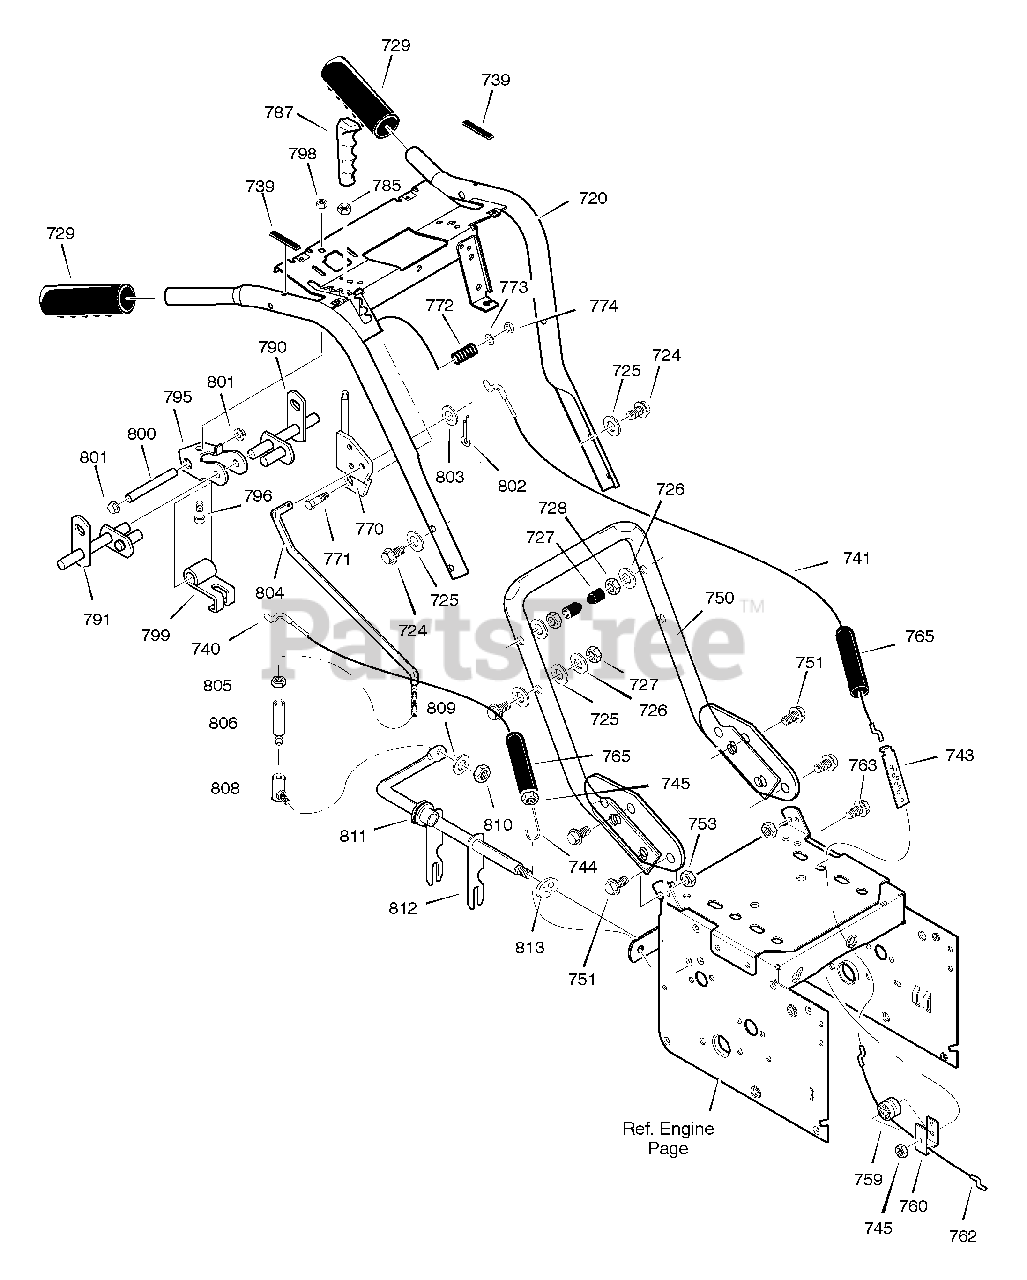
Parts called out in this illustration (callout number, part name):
720	ASSY, HANDLE
724	SCREW
725	WASHER, FLAT
726	WASHER
727	NUT
728	STOP, PLASTIC
729	GRIP, HANDLE
739	BUMPER
740	CABLE, AUGER CLUTCH
741	CABLE, DRIVE
743	BRKT, CABLE ADJ
744	SPRING, CLUTCH
745	NUT, HEX
750	HANDLE, LOWER
751	SCREW
759	SPOOL, CABLE
760	BRKT, SPOOL
762	CABLE, LOWER DRIVE
763	BOLT, HEX 1/4-20 x 1.5
765	BOOT, CABLE
770	BRACKET, SHIFT
771	SCREW
772	SPRING
773	WASHER, FLAT
774	NUT, HEX
785	NUT, HEX
787	KNOB, SHIFT
790	ROD, ASSY LH
791	ROD, ASSY RH
795	BRACKET, CAM
796	SCREW
798	NUT, NYLOCK
799	CAM LOCK
800	PIN, SPRING PIVOT
801	NUT, PUSH ON
802	PIN, COTTER
803	FLATWASHER
804	ROD, SPEED CONTROL
805	NUT, 5/16-18
806	ADAPTER, ROD
808	BALLJOINT, STEEL
809	WASHER
810	NUT, 5/16-18
811	BEARING, FL
812	ROD, YOKE
813	RETAINER, RING
